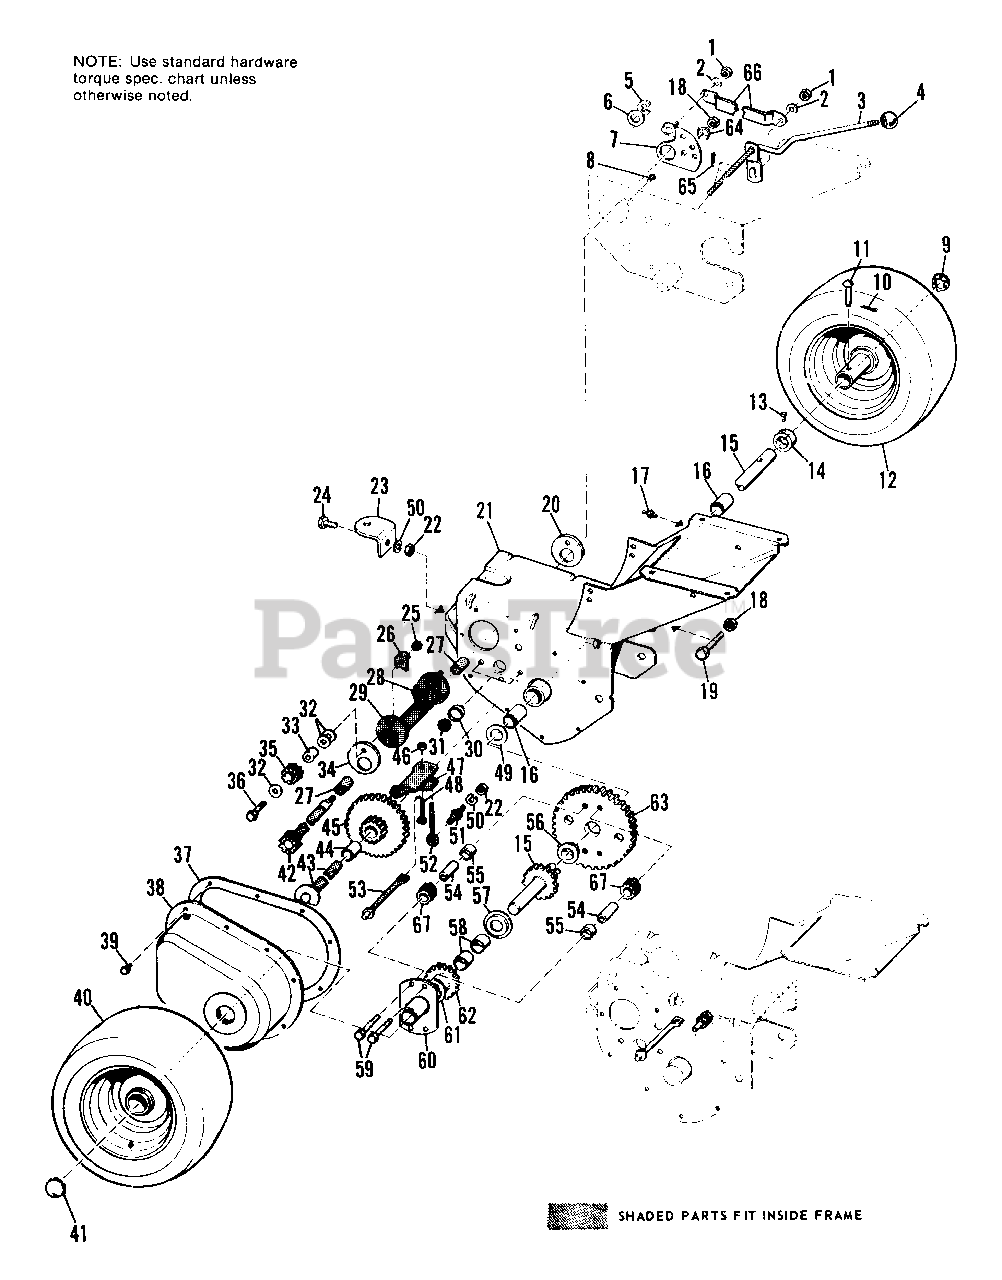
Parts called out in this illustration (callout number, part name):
1	LOCKNUT, 5/16-18
2	WASHER, Plain, 1/4
3	LEVER ASSY., Shift
5	RING, Retaining
7	LEVER ASSY., Detent
8	SCREW, Rd. Hd., 12-24 x 1/2
9	BUTTON, Plug
10	PIN, Cotter, 1/8 x 3/4
11	PIN
12	WHEEL & TIRE ASSY., L.H.
13	SETSCREW, Cup Pt., Sq. Hd., 5/16-18 x 3/18
14	COLLAR, Set
15	AXLE SHAFT, L.H.
17	FITTING, Grease
18	LOCKNUT, 3/8-16
19	CAPSCREW, Hex Hd., 3/8-16 x 2-3/4
21	ENGINE BASE, FRAME & SEAT SUPPORT ASSY.
22	NUT, Hex, Full, 3/8-16
23	BAR, Draw
24	CAPSCREW, Hex Hd., 3/8-16 x 1
25	NUT, Hex, Full, L.H. 3/8-16
26	PLATE, Lock
28	FITTING, Grease
29	HOUSING ASSY., Bearing
30	RETAINER, Brake Lining
31	LINING, Brake
32	WASHER, Plain, 5/16
33	SPACER, Pinion
35	PINION, Reverse
36	CAPSCREW, Hex Hd., 3/8-16 x 1-1/2 L.H. Thd.
38	GEAR CASE ASSY.
39	SCREW, Hex, Washer Hd., Taptite, 1/4-20 x 3/8
40	WHEEL & TIRE ASSY., R.H.
41	BUTTON, Plug
42	SHAFT ASSY., Pulley
43	SHAFT ASSY., Intermediate
44	BEARING, Pinion
45	GEAR ASSY. Intermediate
46	LOCKNUT, Hex, 1/4-20
47	ARM, Brake
48	CAPSCREW, Hex Hd., 1/4-20 x 1-1/2
50	LOCKWASHER, 3/8
52	PIN, Lock
53	PIN, Anchor
54	SPINDLE, Diff.
55	SPACER, Diff.
56	BUSHING, Drive Gear
57	CUP, Thrust
59	CAPSCREW, Hex Hd., 3/8-16 x 2
60	PLATE, Diff.
62	AXLE & BUSHING ASSY., R.H.
63	GEAR. Drive
64	SPRING. Conical
65	PIN, Cotter. 1/8 x 1
66	LINK, Shaft
67	PINION, Diff.
